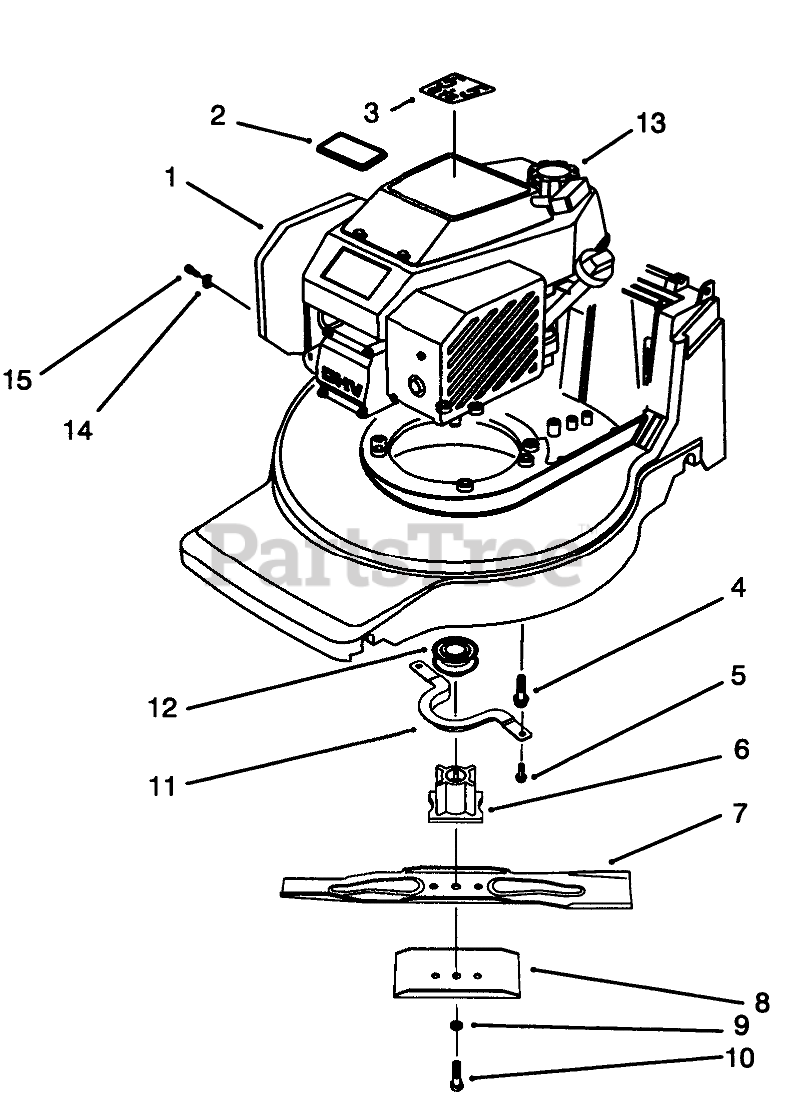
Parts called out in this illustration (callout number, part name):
1	ENG ASM-GTS150 KEY/NC
2	PLATE-LOGO
3	DECAL - ENGINE
4	SCREW-HWH
5	SCREW-HWH
6	BLADE RETAINER - 25 MM
7	Blade
8	Stiffener Blade
9	WASHER-LOCK
10	BOLT-BLADE
11	Guide-Belt
12	PULLEY-DRIVE, ZONE START
13	GAS CAP ASM
14	CLAMP-CASING
15	CLAMP SCREW F/W ENGINE
